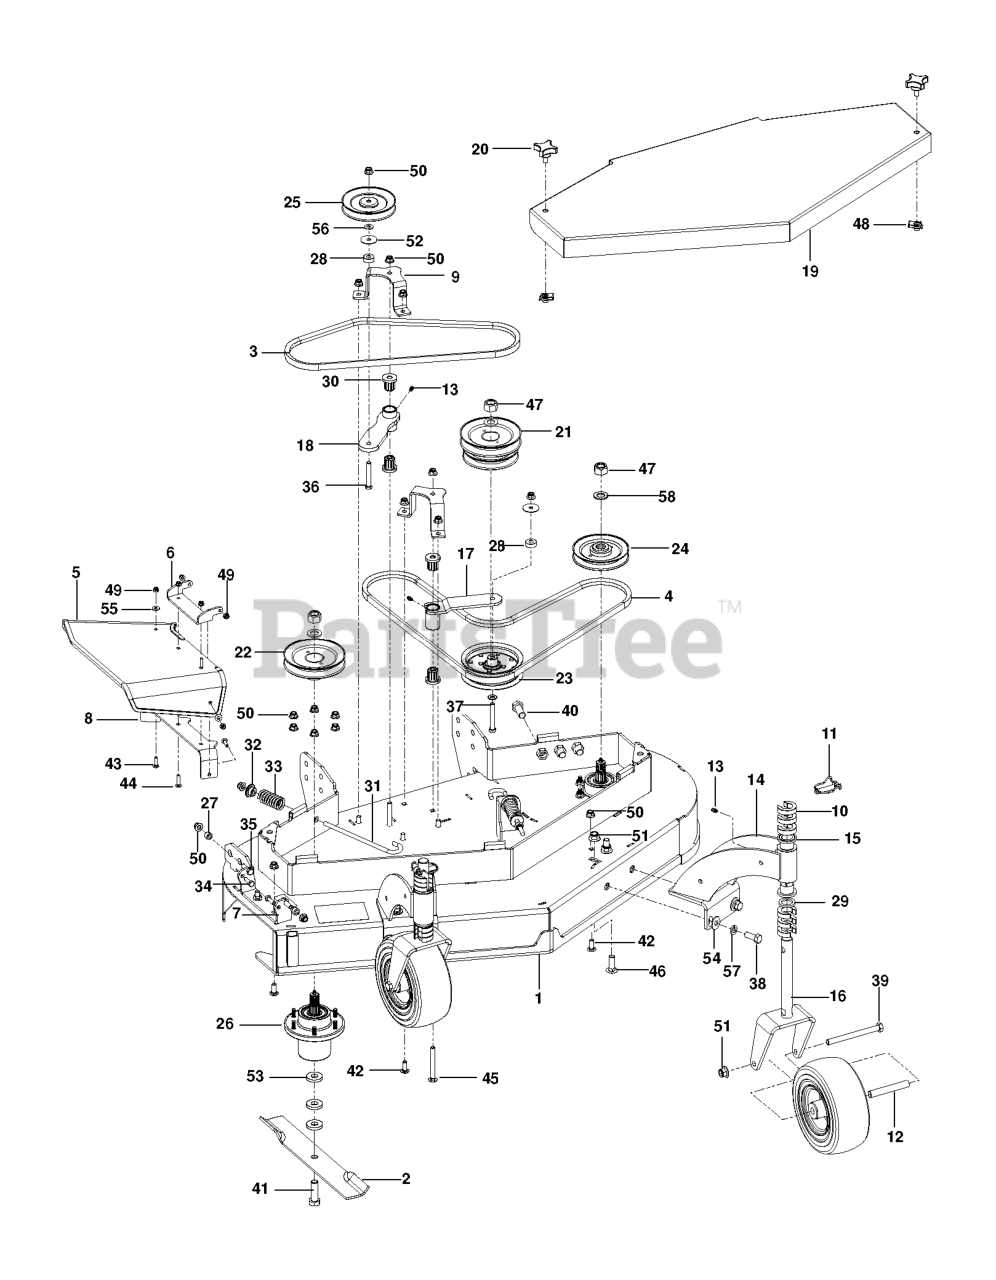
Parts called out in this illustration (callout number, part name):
1	DECK ASSY ASSY, DECK 48" GEAR
2	BLADE, 16.500 X .80 LIFT
3	BELT BELT, HB 51.4 EL AMD
4	BELT BELT, HB WRAPPED 83.2" EL
5	CHUTE CHUTE, DISCHARGE RUBBER
6	BRACKET BRACKET, DISCHARGE MOU
7	BRACKET BRACKET, DISCHARGE PIV
8	BRACKET BRACKET, DISCHARGE
9	BRACKET BRACKET, IDLER
10	SPACER C-SPACER, 1.00 X 1.77 X
11	PIN PIN, LNC .438 X 2.00
12	TUBE TUBE, CASTER AXLE
13	FITTING FITTING, 1/4-28 STRGT
14	STRUT STRUT FRONT FXWLK HUSQ
15	BEARING BRG, FLG 1.00 X 1.25 X
16	YOKE CASTER YOKE HUSQ
17	OFFSET PULLEY IDLER ARM WITH O
18	OFFSET PULLEY IDLER, 36 FXWLK
19	SHIELD SHIELD 48"
20	KNOB KNOB, 3/8 -16 X .75
21	PULLEY PULLEY CNT SPN DBL BLT
22	PULLEY PULLEY RH SPN DBL BLT
23	PULLEY PULLEY, FLAT 5.00 X .37
24	PULLEY PULLEY, SPINDLE .25 HUB
25	PULLEY PULLEY, IDLER 5.0 V-GRO
26	SPINDLE ASSY, SPINDLE HOUSING
27	BUSHING BUSHING, SLV
28	BUSHING BUSHING, .380 X 1.00 X
29	BUSHING BUSHING, 1.03 X 1.50 X
30	BEARING BRG, FLG M10 X M25 X M
31	BOLT J-BOLT, 3/8-16 X 7.88
32	KEEPER KEEPER, SPRING
33	SPRING SPRING, COM 1.22 X .162
34	BOLT BOLT HEX .31-18 X 1.00 GR
35	BOLT BOLT HEX .38-16 X 1.25 GR
36	BOLT BOLT-HEX .38-16X2.50 GR5
37	BOLT BOLT HEX .38-16 X 2.75 GR
38	BOLT BOLT HEX .50-13 X 1.25 GR
39	BOLT BOLT HEX .50-13 X 5.50 G
40	BOLT BOLT, HEX 5/8-11 1.5" GR8
41	BOLT BOLT HEX .62-11 X 2.00 G
42	BOLT BOLT RDHDSHSQNK .38-16 X
43	BOLT BOLT RDHDSQNK .31-18 X 1.
44	BOLT BOLT RDHDSQNK .31-18 X 1.
45	BOLT RDHDSQNK .38-16 X 3.
46	BOLT BOLT RDHDSQNK .50-13 X 1.
47	LOCK NUT LOCKNUT, 3/4-16 CROWN
48	NUT NUT, RTNR .375-16 X .37
51	NUT NUT, LK-NYL-FLG .50-13 YWZ
52	WASHER WASHER, FL-STL .38 X 1.
53	WASHER WASHER, FL-STL .630 X 1
54	WASHER WASHER, FL-STL .50 X 1.
55	WASHER WASHER, FL-STL .38 X .8
57	WASHER WASHER, LK .50X.125 REG
58	WASHER WASHER, .75 X 1.3125 X
